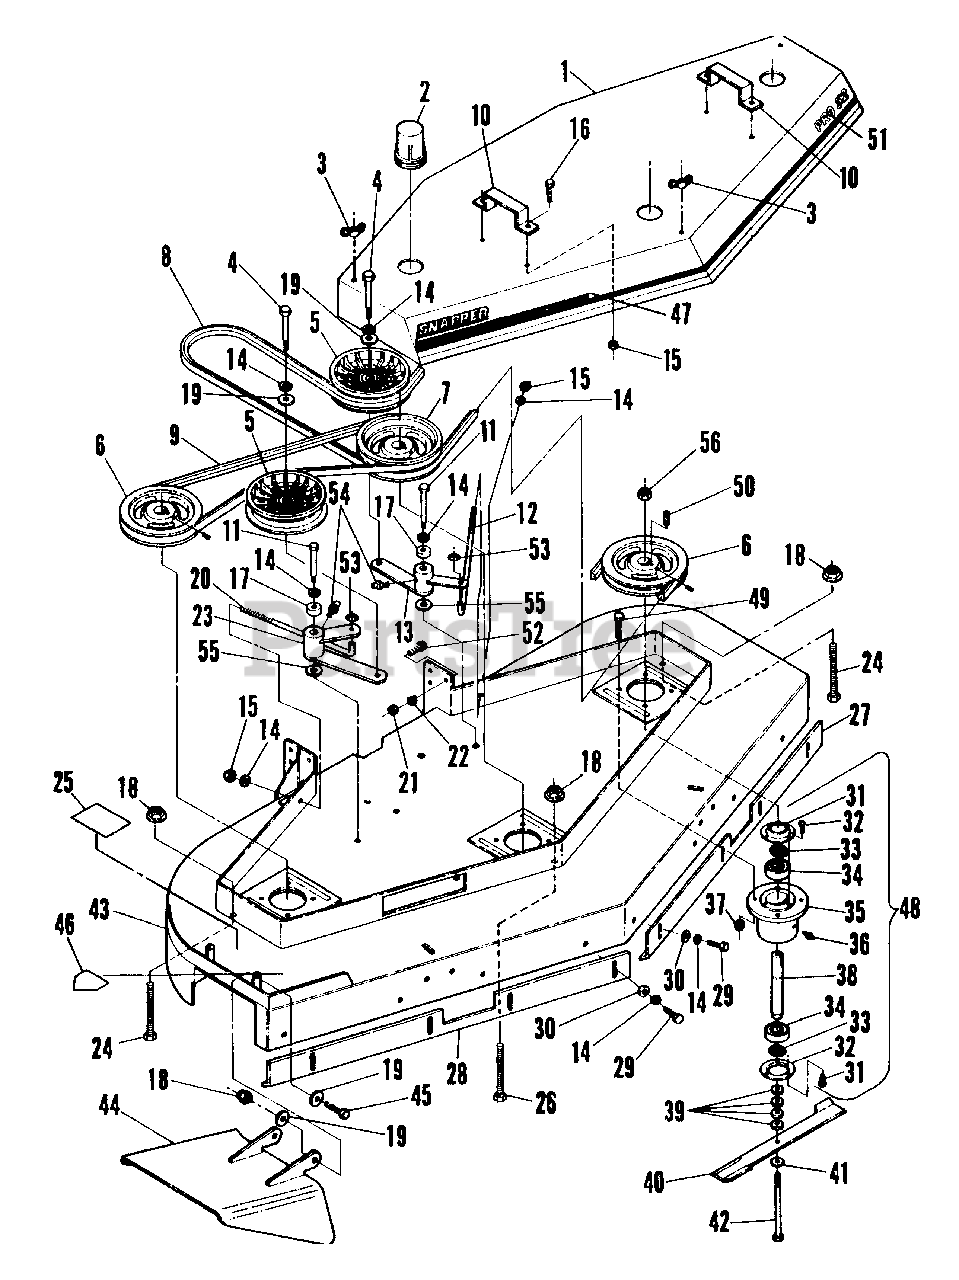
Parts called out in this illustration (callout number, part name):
1	HOOD w/Decals 52
2	CAP, Spindle
3	WING-NUT, 3/8-16 Nyloc
4	SCREW, 3/8-16 x 1-3/4" Hex Head Cap, Grade 8
5	PULLEY, Idler
6	PULLEY, w/Set Screws
7	PULLEY, Double w/Set Screws
8	BELT, Engine to Deck
9	BELT, Cutter Spindle
10	HANDLE, Hood
11	SCREW, 3/8-26 x 3-1/4" Hex Head Cap, Grade 5
12	ROD, Belt Adjusting
13	ARM, Engine to Deck Idler Weldment
14	WASHER, 3/8" Split Lock
15	NUT, 1/4-20 Hex Nyloc
16	SCREW, 1/4-20 x 5/8" Hex Head Cap, Grade 5
17	SPACER, Pivot
18	NUT, 3/8-16 Hex Flange lock
19	WASHER, 3/8" Flat
21	NUT, 1/2-13 Hex
22	WASHER, 1/2" Lock
23	ARM, Blade to Blade Idler Weldment
24	TAP BOLT, 3/8 x 5"
25	DECAL, Caution
26	TAP BOLT, 3/8 x 4"
27	SKIRT, Front L.H.
28	SKIRT, Front R.H.
29	SCREW, 3/8-16 x 3/4" Hex Head Cap, Grade 5
30	WASHER, 3/8" Flat
31	CAP, Cutter Housing
32	SCREW, #10-24 x 1/2" Hex Washer Self-Tap
33	RING, Retaining
34	BEARING, Single Seal
35	HOUSING, Cutter
36	FITTING, 1/8" NPT Grease
37	NUT, 3/8-16 Hex Nyloc
38	SPINDLE, Cutter
39	SPACER, Blade
40	BLADE, 18" High Lift
41	WASHER, 5/8" Bevel
42	SCREW, 5/8-18 x 8-1/2 Hex Head Cap, Grade 5
43	DECK, 52" Mowing
44	DEFLECTOR, Chute
45	SCREW, 3/8-16 x 1" Hex Head Cap, Grade 5
46	DECAL, Warning
47	DECAL, 52 Hood
48	HOUSING, Asy. Cutter
49	SCREW, 3/8-16 x 1-1/4" Hex Head Cap, Grade 5
50	KEY, Spindle
51	DECAL, Pro 52
52	BOLT, 1/2-13 x 1-1/4" Hex Flange Lock
53	RETAINER, 3/8" Rod
54	FITTING, Grease
55	BUSHING, 1" x 14 Ga. Machine
56	NUT, 5/8-18 Hex
